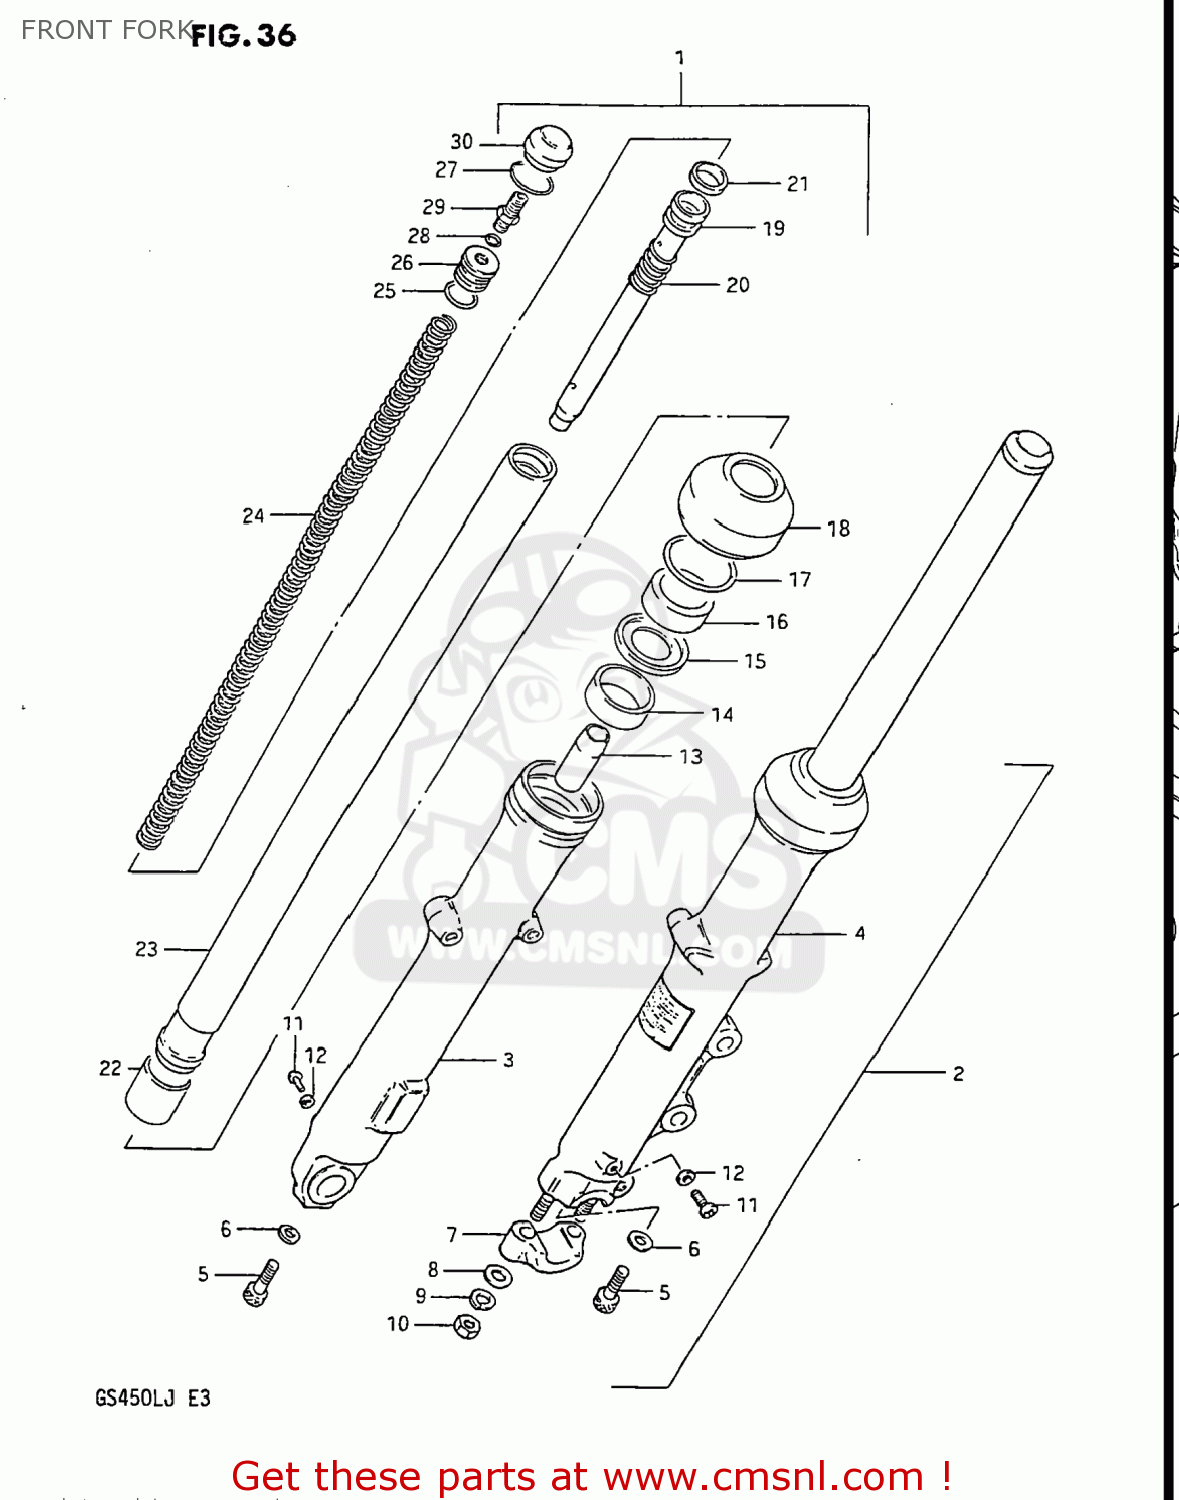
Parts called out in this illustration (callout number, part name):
1	DAMPER ASSEMBLY,FRONT FORK,RIGHT
2	DAMPER ASSEMBLY,FRONT FORK,LEFT
3	TUBE,FORK,OUTER,RIGHT
4	TUBE,FORK,LEFT,OUTER
5	BOLT(8X27)
6	GASKET (NAS)
7	HOLDER,AXLE
8	WASHER
9	LOCK WASHER
10	NUT (8MM)
11	BOLT
12	GASKET,DRAIN,PLUG (NAS)
13	PIECE,OIL LOCK
14	BUSH,GUIDE
15	SPACER,SEAL
16	OIL SEAL,FRONT FORK
17	CIRCLIP,FORK OIL SEAL
18	DUST SEAL,FR FORK
19	CYLINDER,FRONT FORK
20	SPRING,FORK REBOUND
21	RING,PISTON
22	PISTON
23	TUBE,FRONT FORK,INNER
24	SPRING,FRONT FORK
25	O RING
26	SEAT,SPRING
27	RING,STOPPER
28	O-RING (D:3.8 ID:19)
29	VALVE,AIR
30	CAP
